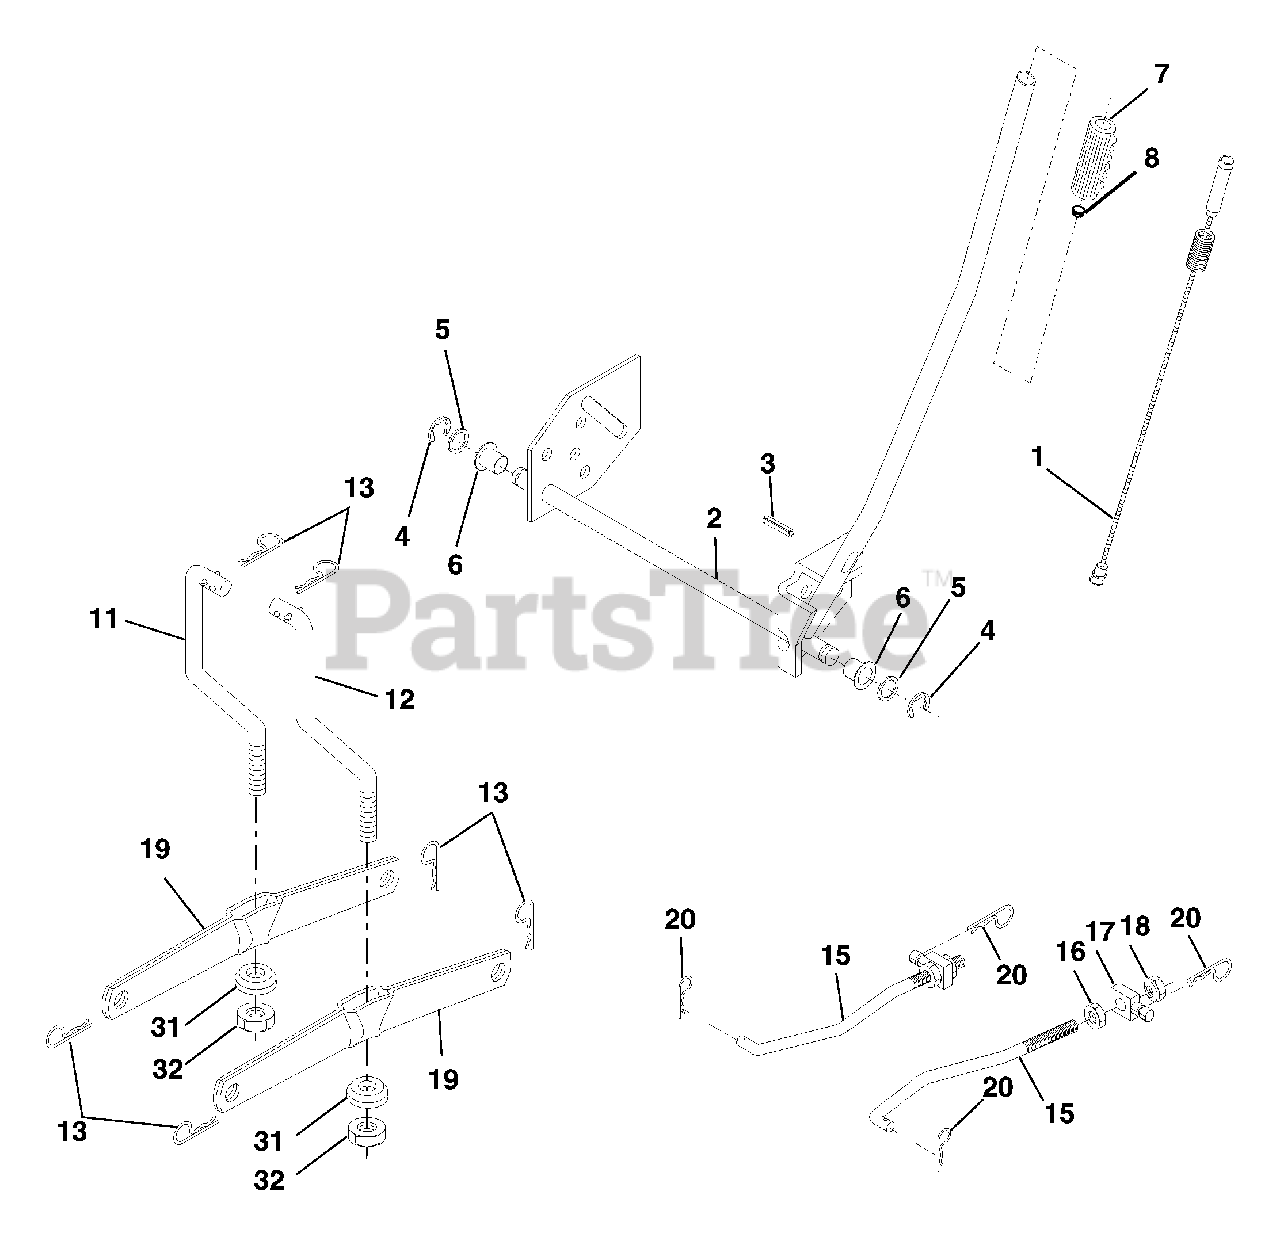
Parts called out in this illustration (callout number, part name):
1	Wire Asm Inner/Sprg W/plunger
2	Shaft Asm Lift RH w/Inf
3	Pin Groove 5/16 x 1.875
4	E Ring #5133-62
5	Washer 21/32 x 1 x 21 Ga.
6	Bearing Nylon Blk 629 Id
7	Grip Handle
8	Button Plunger
11	Link Lift LH Fixed Length
12	Link Lift RH Fixed Length
13	Retainer Spring
15	Link Front
16	Nut Jam Hex 1/2-13 unc
17	Trunnion
18	Nut Lock W/Wsh 1/2-13 unc
19	Arm Suspension Rear
20	Retainer Spring
31	Bearing Pvt Lift
32	Nut Crownlock 3/8 - 24
